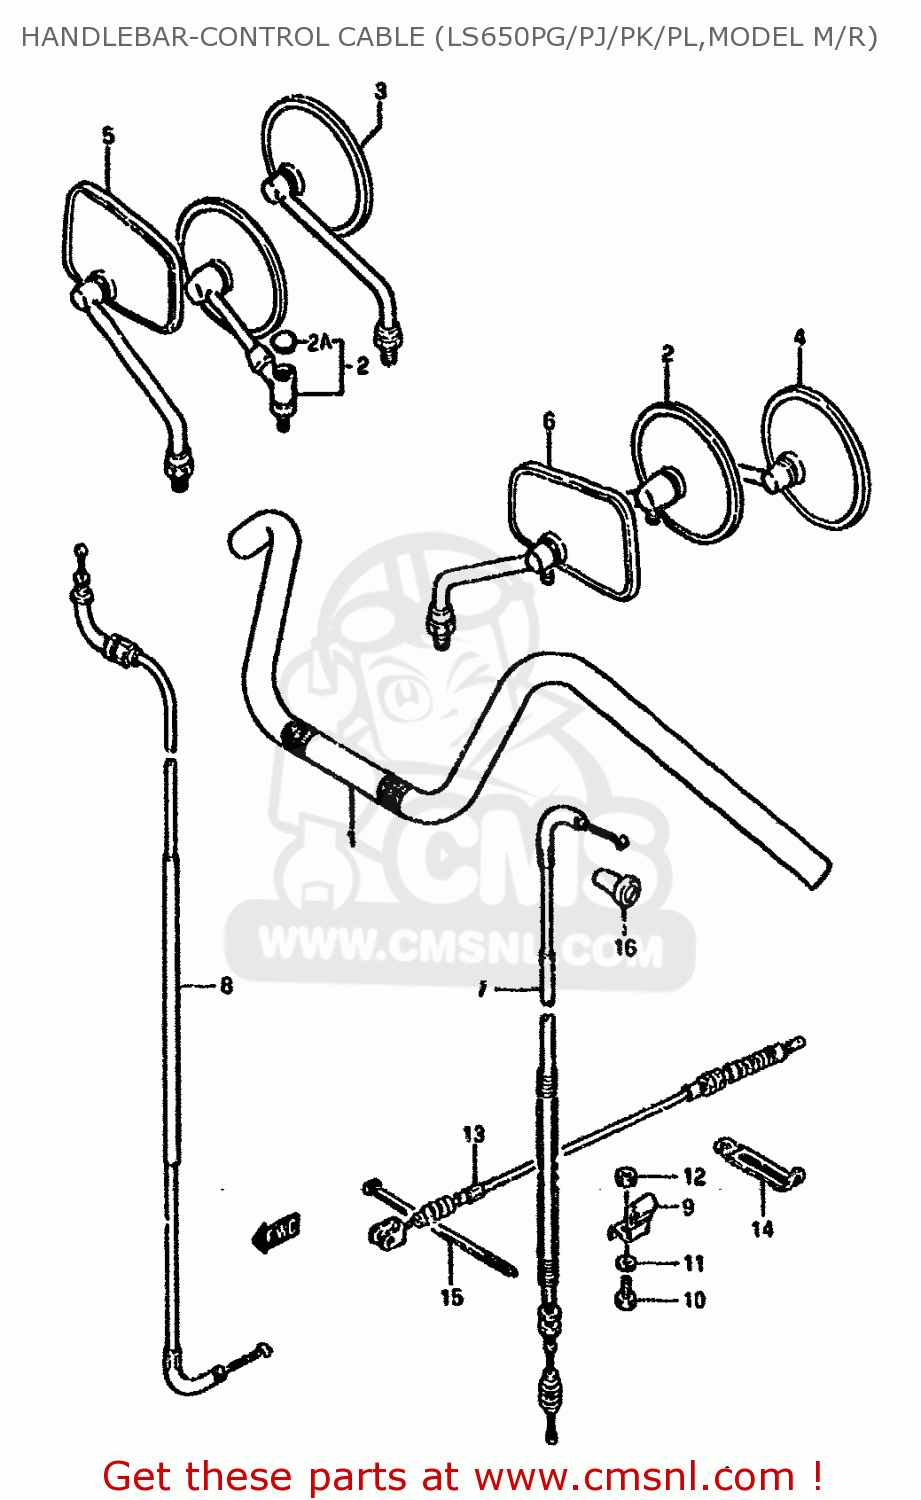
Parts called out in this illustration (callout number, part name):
1	HANDLEBAR
2	MIRROR ASSY,RH
2A	CAP
3	MIRROR ASSY,REAR VIEW RH
4	MIRROR ASSY,REAR VIEW LH
5	MIRROR ASSEMBLY,REAR VIEW
6	MIRROR ASSEMBLY,REAR VIEW
7	CABLE ASSY,CLUTCH
8	CABLE ASSY,THROTTLE
9	GUIDE,CABLE
10	BOLT
11	WASHER,LOCK
12	NUT
13	CABLE COMP,STOP LAMP SWITCH
14	CLAMP
15	CLAMP
16	BOOT,CLUTCH CABLE
